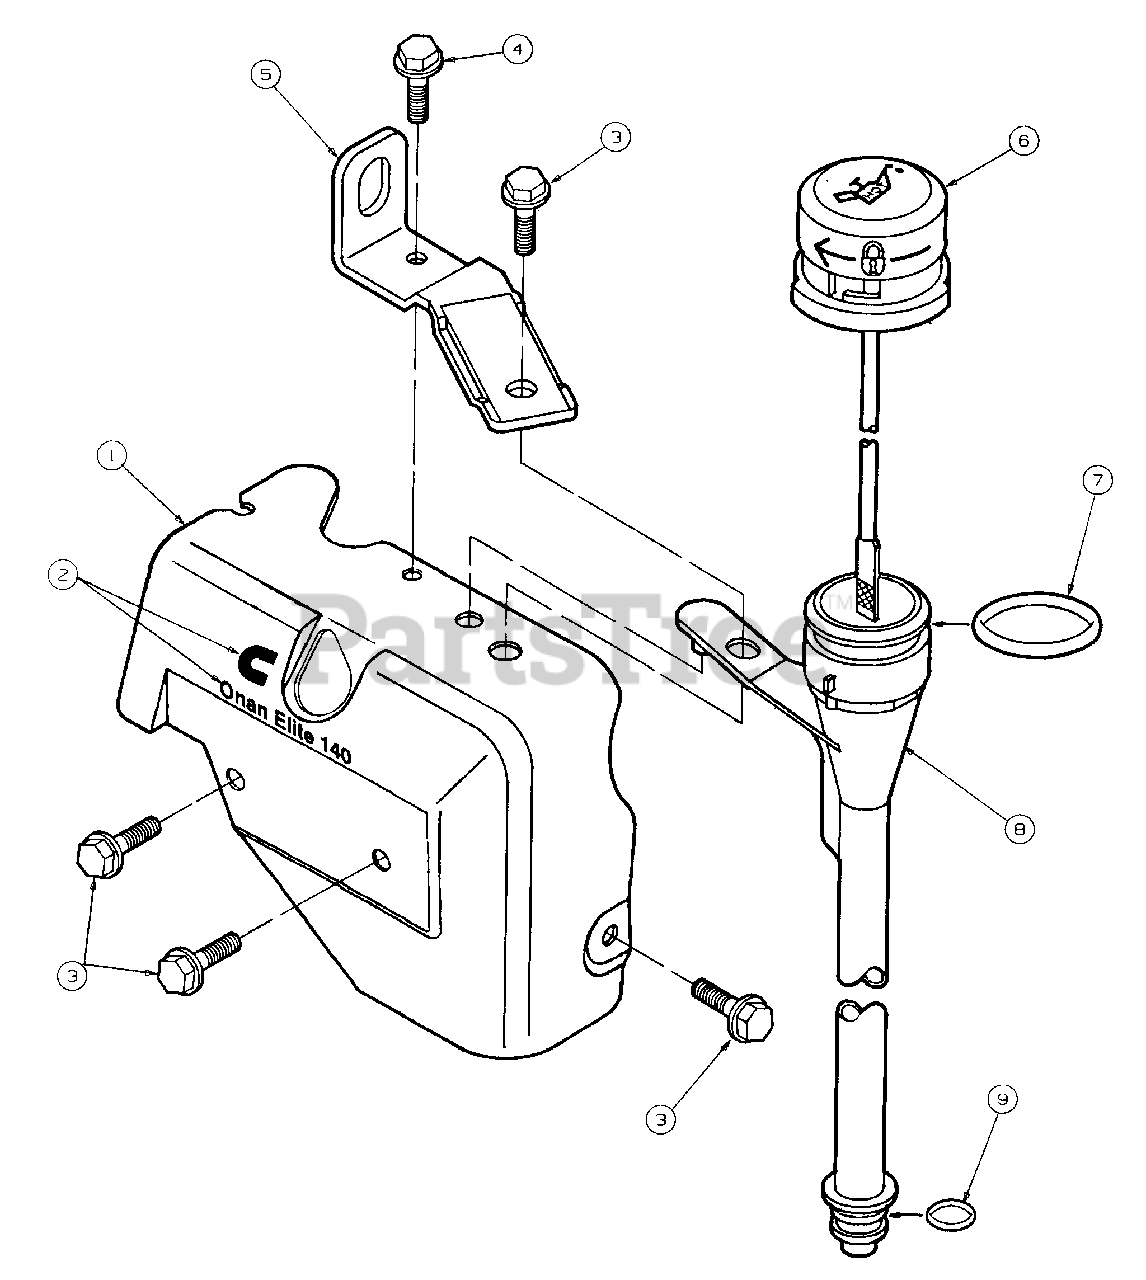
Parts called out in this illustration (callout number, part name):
1	Housing, Air Cylinder
2	Label, Model Ident
3	Screw, Hex Head Flange, Thread Forming, M8 x 1.25 x 16 mm
4	Screw, Flange Lock M6 x 1 x 16 mm
5	Bracket, Lift
6	Indicator & Cap Assy
7	O-Ring, Upper
8	Tube, Oil Fill
9	O-Ring, Lower
